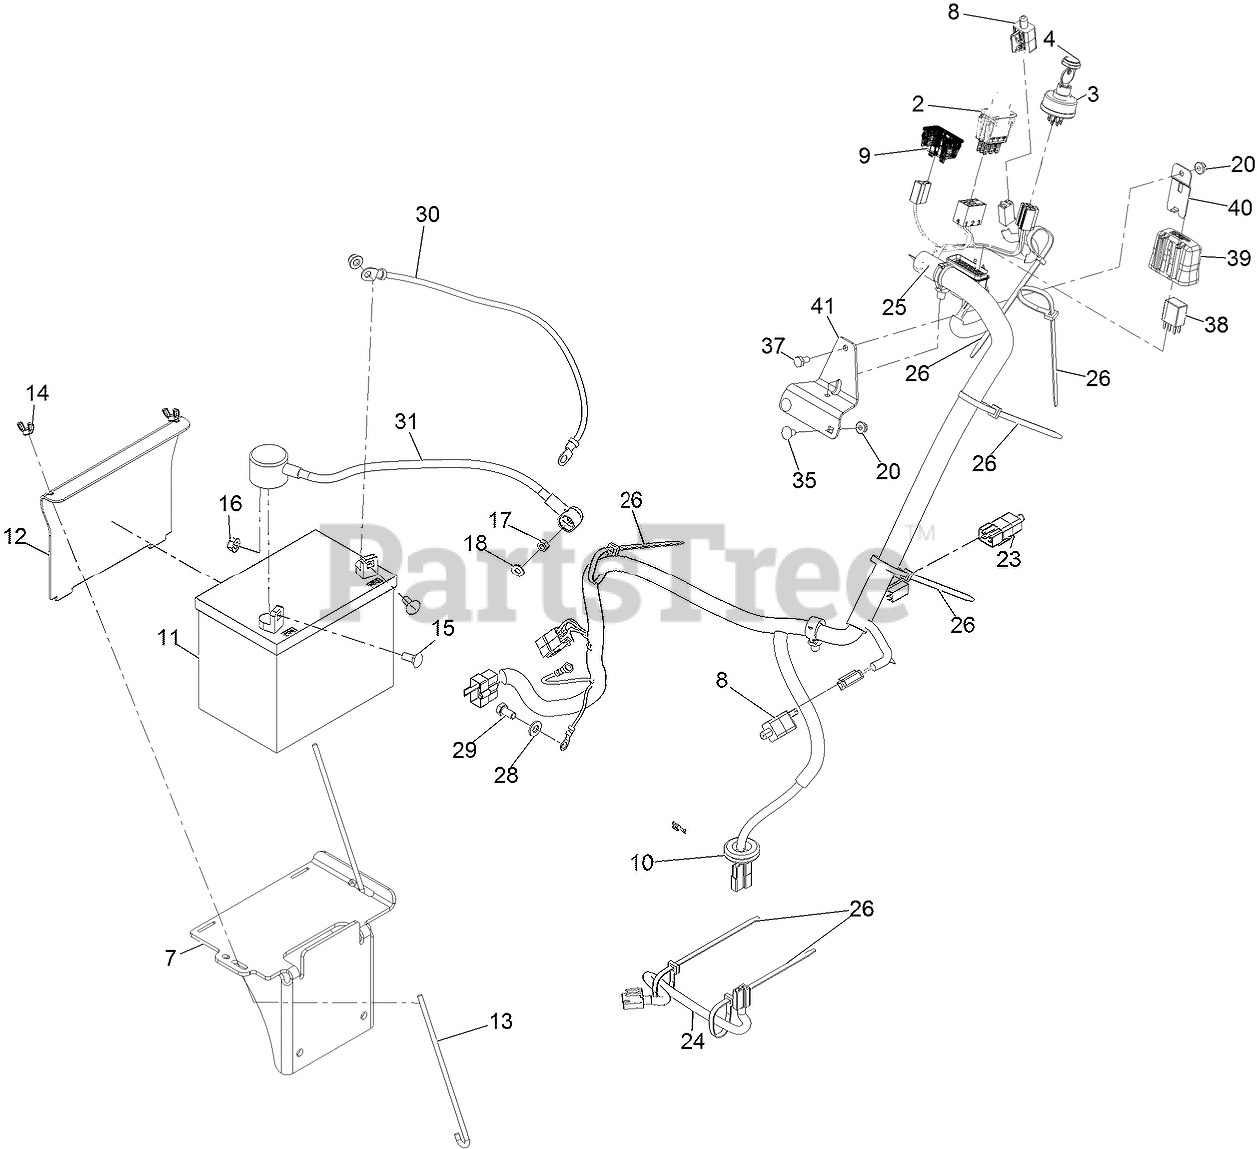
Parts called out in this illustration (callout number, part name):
2	SWITCH-PTO
3	SWITCH, KEY START
4	NUT-SWITCH, IGNITION
7	WELD, BATTERY MOUNT
9	METER-HOUR
10	GROMMET
11	Battery
12	BRACKET, BATTERY HOLD DOW
13	BOLT-HOLDDOWN
14	WINGNUT
15	BOLT-CARR
16	NUT-HF, NI
17	NUT-HEX
18	WASHER-FLAT
23	SWITCH, 2 POLE
24	HARNESS-CLUTCH PIGTAIL
25	HARNESS-WIRING
26	TIE-PLASTIC
28	WASHER-PLAIN
29	SCREW-HH
31	ASM,POSITIVE BATTERY CABL
35	SCREW-CARR
37	SCREW-HH
38	RELAY-MICRO 280, SPDT
39	COVER-BLOCK, FUSE
40	CLIP-MOUNTING
41	BRACKET-MOUNTING, FUSEBLO
